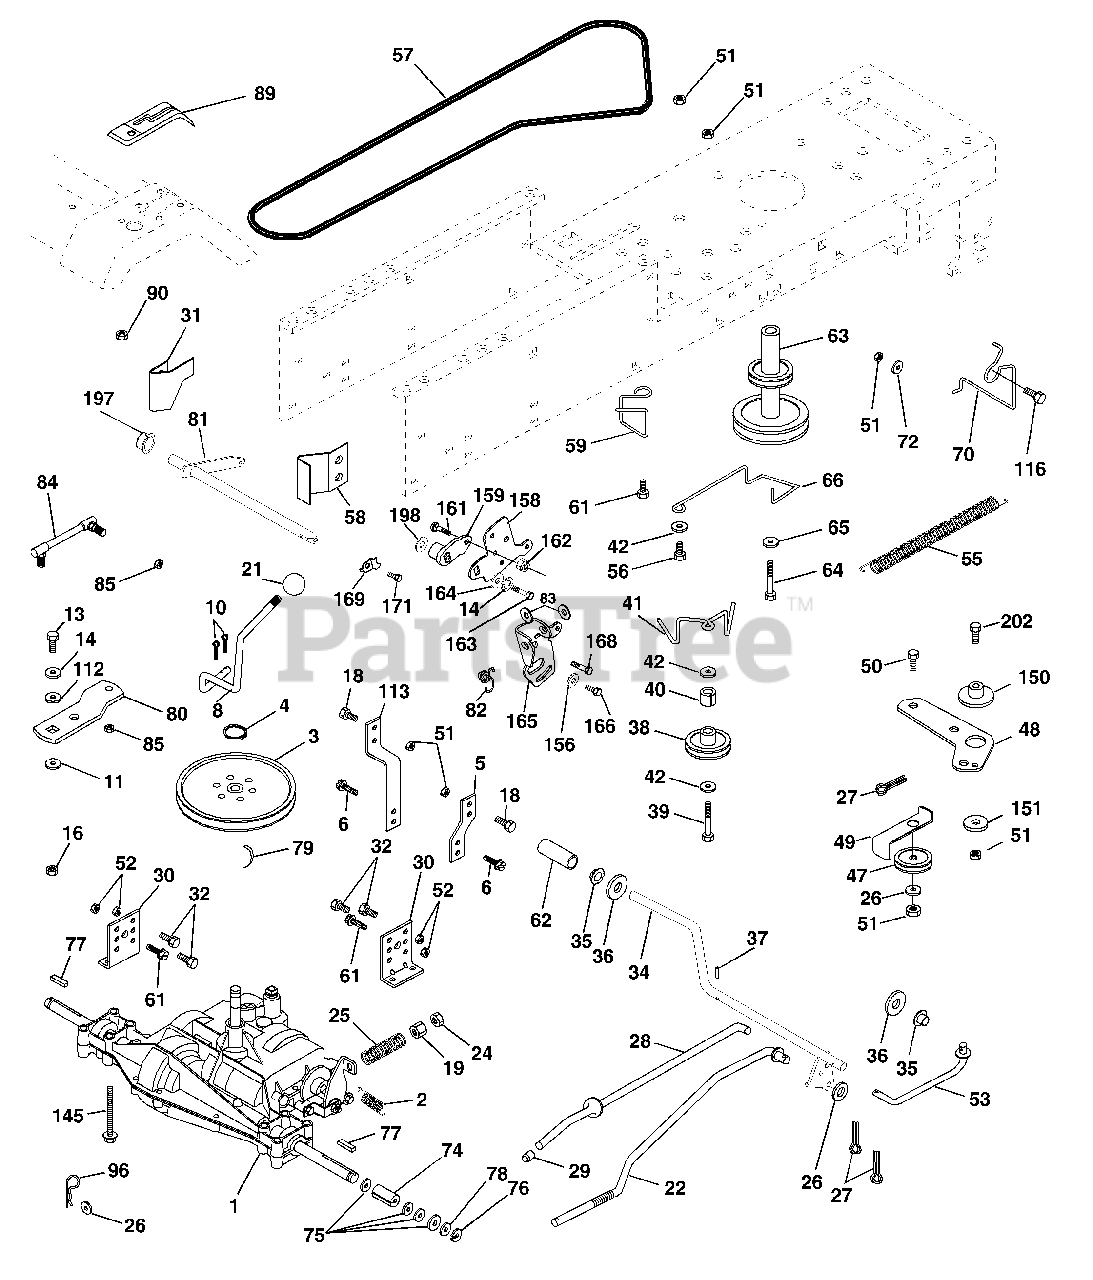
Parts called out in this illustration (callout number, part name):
2	Spring Return Brake T/a Zinc
3	Pulley Transaxle 18" tires
4	Ring Retainer # 5100-62
5	Strap Torque 30 Degrees
6	Screw 5/16-18 x 3/4
8	Rod Shifter Fender Adj Lt
10	Pin Cotter 1/8 x 1 Cad
11	Washer Plate Shf 388 Sq Hole
13	Bolt 1/4-28 Unf Gr 8 W/Patch
14	Washer Lock Hvy Helical 1/4
18	Bolt, Fin Hex 3/8-16 UNC x 1 Gr. 5
19	Nut Lock 3/8-16 Unc
22	Rod Brake Blk Zinc 26 840
24	Nut Hex Jam 3/8-16 Unc
25	Spring Rod Brake 2 00 Zinc
26	Washer 13/32 X 13/16 X 16 Ga
27	Pin Cotter 1/8 X 3/4 Cad
28	Rod Brake Parking LT/YT
29	Cap Brake Parking
30	Bracket Mtg Transaxle
31	Keeper Belt LH LT 14 Ga
32	Bolt Hex Hd 5/16-18unc X 3/4
34	Shaft Asm Pedal Foot
35	Bearing Nylon Blk 629 Id
36	Washer 21/32 X 1 X 16 Ga
37	Pin Roll 3/16 X 1"
38	Pulley Idler Flat
39	Bolt Fin Hex 3/8-16unc X 2-3/4
40	Spacer Split 395 X 59 Bzp
41	Keeper Belt Retainer Idler
42	Washer 13/32 X 13/16 X 12 Ga
47	Pulley Idler V Groove Plastic
48	Bellcrank Asm
49	Retainer Belt Style Spring
50	Bolt Hex Hd 3/8-16unc X 1-1/2
51	Nut Crownlock 3/8-16 Unc
52	Nut Crownlock 5/16-18 Unc
53	Link Clutch
55	Spring Return Clutch 6 75
56	Bolt Fin Hx 3/8-16 X 1-1/4
57	V-Belt Ground Drive
58	Keeper Belt RH LT Pnt/zinc 16g
59	Keeper Belt Span Ctr
61	Screw 3/8-16 x 3/4
62	Cover Pedal Blk Round
63	Engine Pulley LT/YT
64	Bolt Hex
65	Washer Lock Hvy Hlcl Spr 7/16
66	Keeper Belt Engine Foolproof
70	Guide Belt Mower Drive RH
72	Washer 13/32 X 1-1/4 X 12 Ga
74	Spacer Axle
75	Washer 25/32 X 1 1/4 X 16 Ga
76	E-ring #5133-75
77	Key Square 2 0 X 1845/ 1865
78	Washer 25/32 X 1-5/8 X 16 Ga
79	Key Woodruff
81	Shaft Asm Cross Tapered 20"t
82	Spring Torsion T/a
83	Washer 17/32 X 3/4 X 16 Ga
84	Link Transaxle
85	Nut Lock Center 1/4 - 28 FNTHD
89	Console Shift STLT
90	Nut Self-thd Wsh-hd 1/4 Zinc
96	Retainer Spring
112	Washer 9/32 x 3/4 x 10 Ga.
113	Strap Torque Lh
116	Bolt Rdhd Sq Neck 3/8-16 x 1.25
145	Bolt Hex 5/16-18 Gr. 5
150	Bushing Bellcrank Grd. Drive
151	Washer 13/32 x 2 x 10
156	Washer Srrted 5/16 ID x 1.125
158	Bracket Shift Mount
159	Hub Tapered Flange Shift lt
161	Bolt Rdhd Sqnk 1/4-20 x 3/4 Gr 5
162	Nut Crownlock 1/4-20 Unc
163	Bolt Hex Fin 1/4-20 Unc x 1 Gr 5
164	Washer 5/8 x .281 x 10 Ga
165	Bracket Pivot Lever
166	Screw 5/16-18 x 5/8
168	Bolt Shoulder 5/16-18 x .561
169	Plate Fastening Lt
171	Screw Thdrol 3/8-16 x 1/2
197	Nyliner, Snap - in
198	Washer, Nyl.
202	Bolt, Carriage 3/8 - 16 x 1
